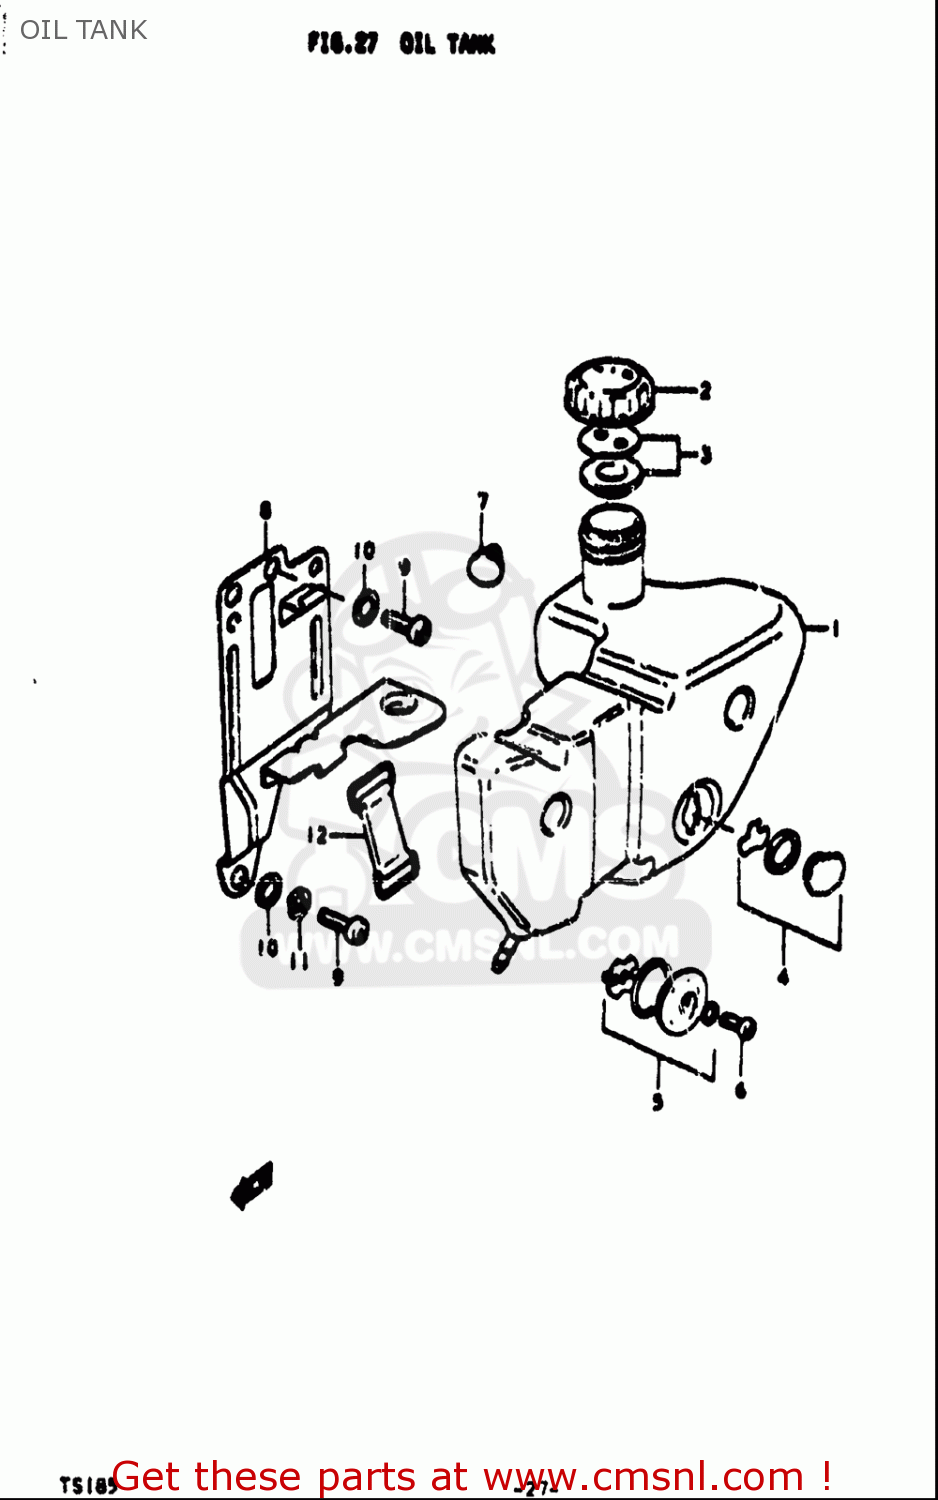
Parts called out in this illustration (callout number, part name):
2	CAP,OIL TANK
3	GASKET SET (NAS)
4	LENS SET,OIL LEVEL
6	SCREW
7	CUSHION
9	SCREW
10	WASHER
11	WASHER,LOCK
12	BAND
